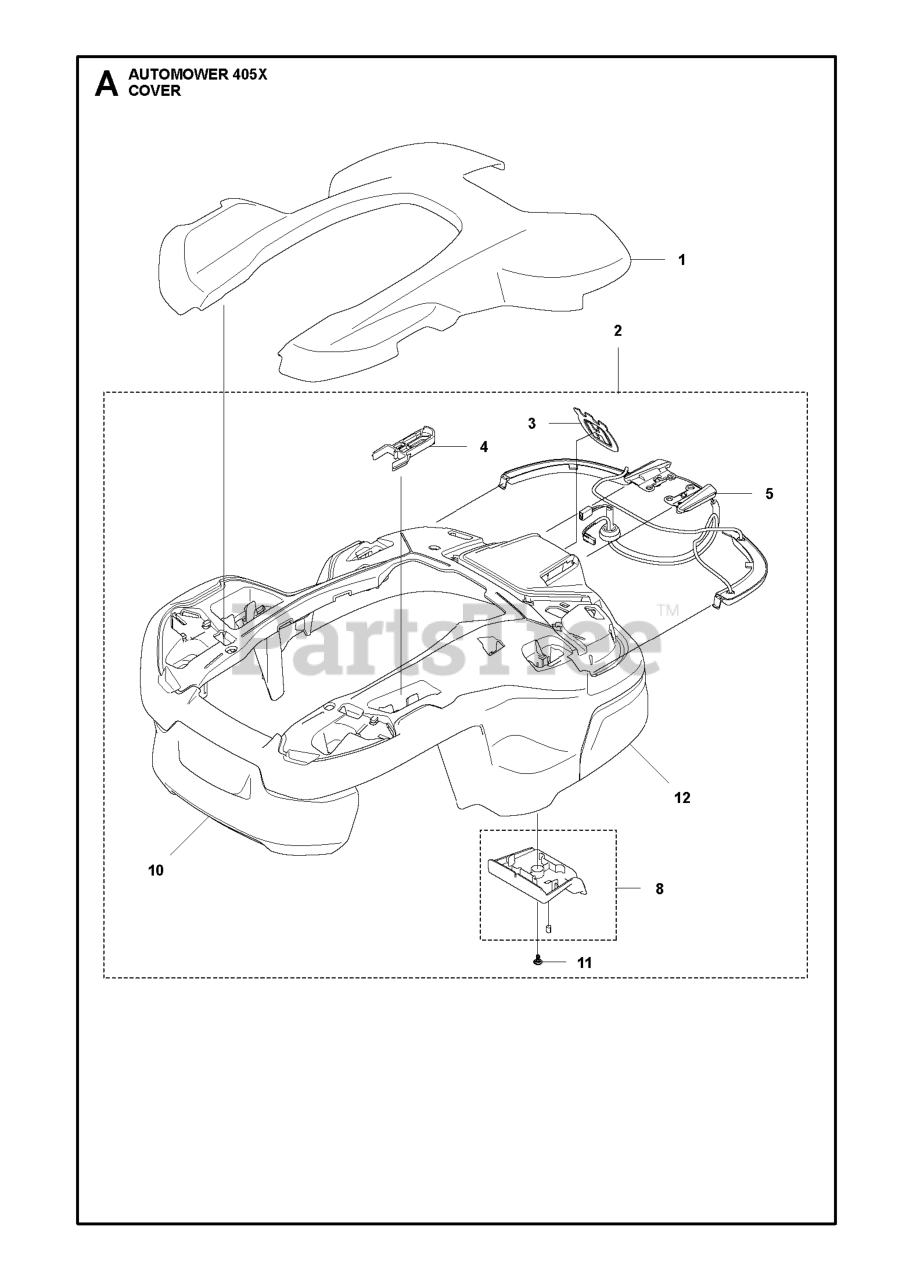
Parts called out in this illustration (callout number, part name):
2	BODY KIT BODY ASSY AM405X / AM
3	DECAL HUSQVARNA CROWN HEIGHT 5
5	WIRING ASSY LED LIGHT AND CHAR
8	HOLDER KIT MAGNET HOLDER AM405
10	BUMPER REAR - P16
11	SCREW ITXPANT
12	BUMPER FRONT 2K - P16
